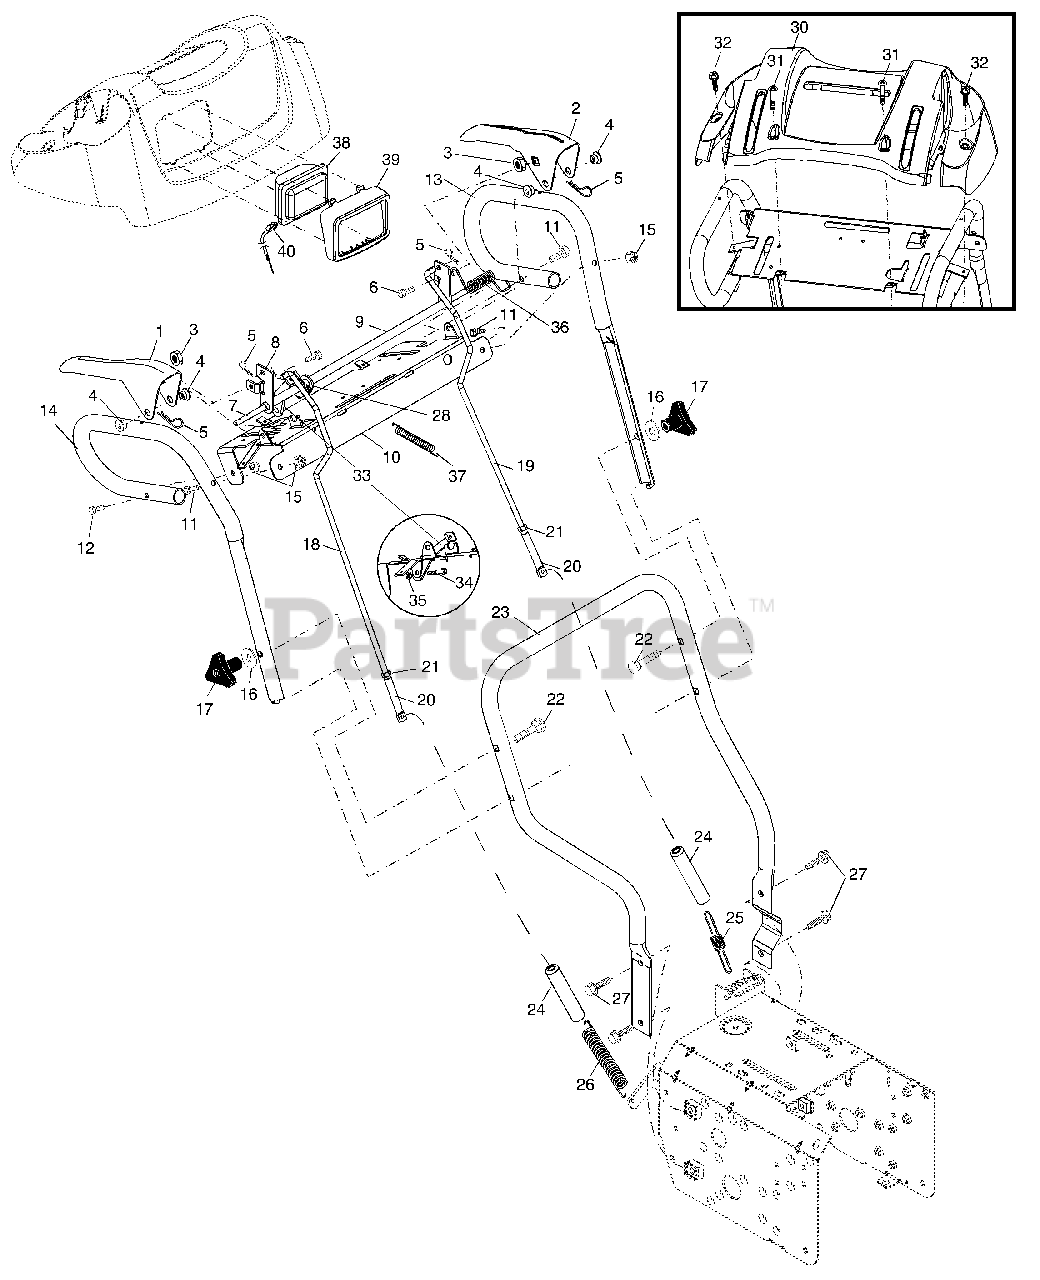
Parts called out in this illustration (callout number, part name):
1	Lever, Auger Control, RH
2	Lever, Traction Drive Control, LH
3	Nut, Cage 1/4-20
4	Bushing, Flange
5	Retainer, Hairpin
6	Screw, Hex Head 1/4-20 x 3/4
7	Rod, Interlock
8	Tube Assembly, Interlock, RH
9	Tube Assembly, Interlock, LH
10	Panel, Control
11	Screw, Hex Head 5/16-18 x 1-1/2
12	Screw, Hex Head 5/16-18 x 1-3/4
13	Handle Tube, LH
14	Handle Tube, RH
15	Nut, Lock 5/16-18
16	Washer, Flat 3/8
17	Knob, Handle
18	Rod, Auger Control
19	Rod, Traction Control
20	End, Control Rod
21	Nut, Hex, Jam 5/16-18
22	Bolt, Carriage 3/8-16 x 2-1/4
23	Handle Tube, Lower
24	Sleeve, Spring
25	Spring, Traction Drive
26	Spring, Auger Control
27	Screw, Hex Head 3/8-16 x 1
28	Clip, Panel
30	Console, Panel
31	Screw, Hex Head, Tapping #10-24 x 1-1/4
32	Screw, Hex Head, Tapping #10-24 x 1/2
33	Latch, Interlock
34	Bolt, Shoulder
35	Nut, Lock 1/4-20
36	Spring, Torsion
37	Spring, Interlock
38	Headlight, Halogen
39	Bezel, Headlight
40	Harness, Headlight (Halogen)
